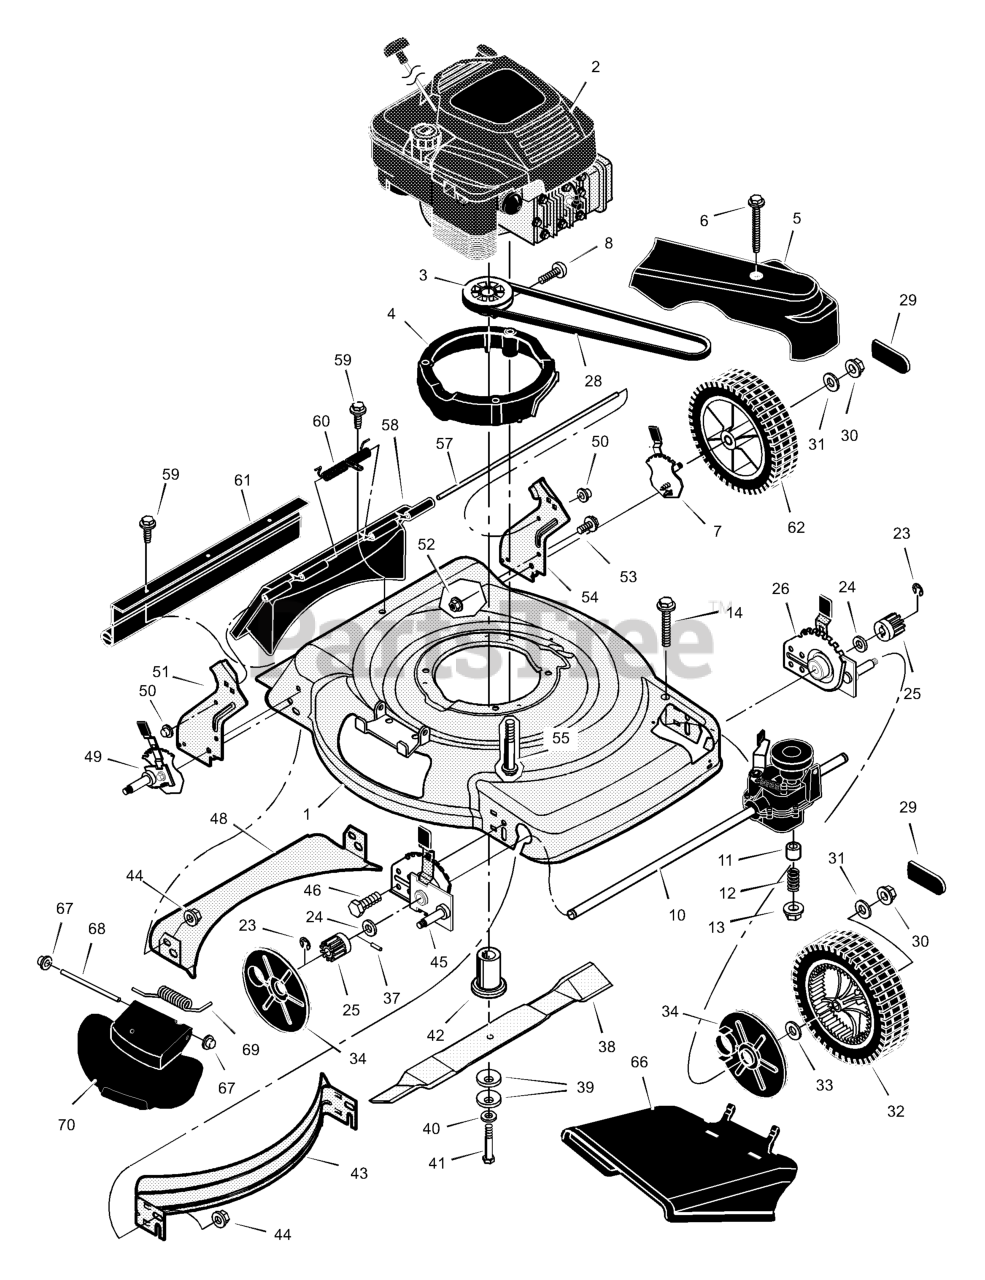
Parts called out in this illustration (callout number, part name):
1	Housing
2	Engine *
3	Pulley, Drive
4	Spacer, Engine
5	Cover, Belt (Black)
7	Adjuster, Left Rear Height
10	Transmission *
12	Spring, Compression
13	Nut
14	Bolt
25	Gear, Pinion
26	Adjuster, Left Front Height
29	Cap, Hub
30	Nut, Flange
31	Washer
32	Wheel & Tire, Drive
34	Cover, Dust
37	Pin, Drive
39	Washer, Belleville
42	Adapter, Blade
43	Baffle, Front
44	Nut, Flange
45	Adjuster, Right Front Height
46	Bolt
48	Baffle, Rear
49	Adjuster, Right Rear Height
50	Push On Cap
51	Bracket, Right Handle
52	Nut, Flange
53	Bolt
54	Bracket, Left Handle
55	Bolt, Engine
57	Rod, Pivot
58	Door, Rear (Gray)
61	Guard, Rear
62	Wheel & Tire, Rear
66	Deflector, Chute
67	Push On Cap
68	Rod, Pivot
69	Spring, Torsion
70	Cover, Mulch (Gray)
